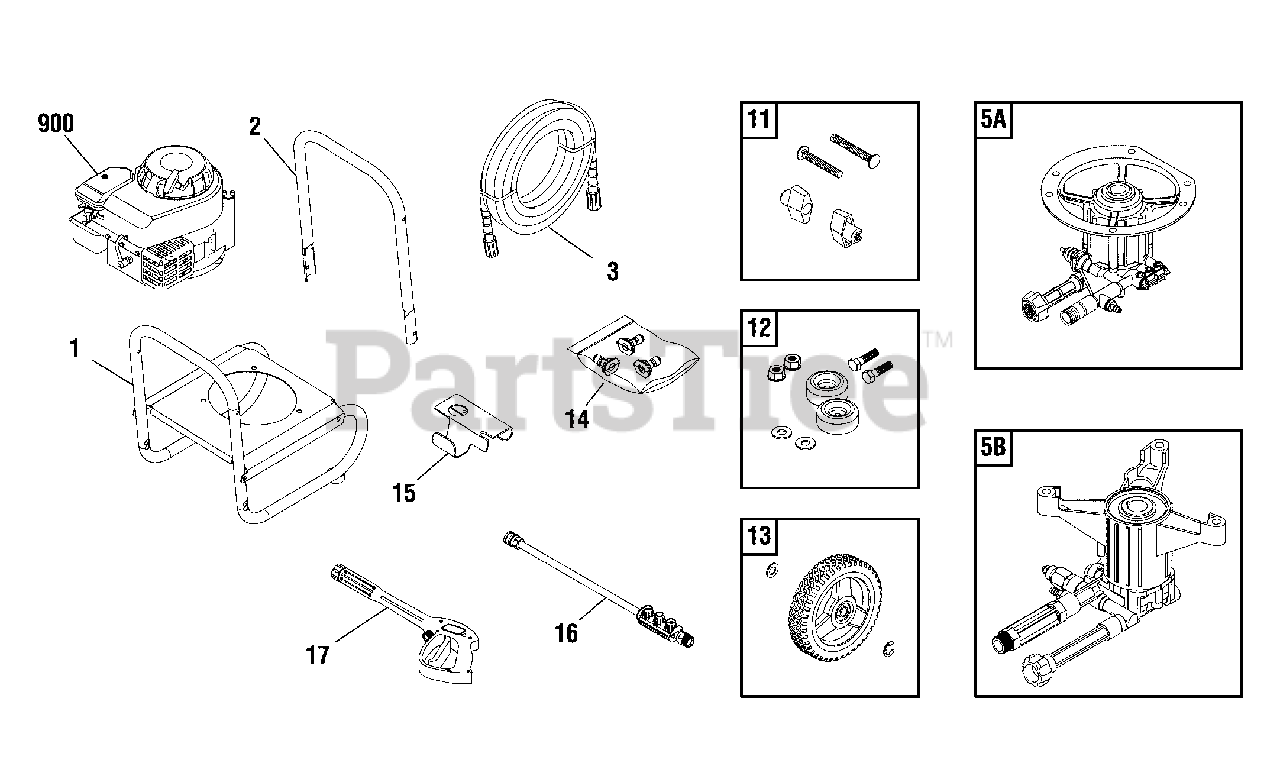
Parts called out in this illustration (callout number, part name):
3	HOSE
5A	PUMP, Complete
11	KIT, Handle Connector
12	KIT, Vibration Mount
14	KIT, Spray Tips
15	HOLDER, Accessory
16	WAND, Nozzle Holder
17	GUN
900	* ENGINE
